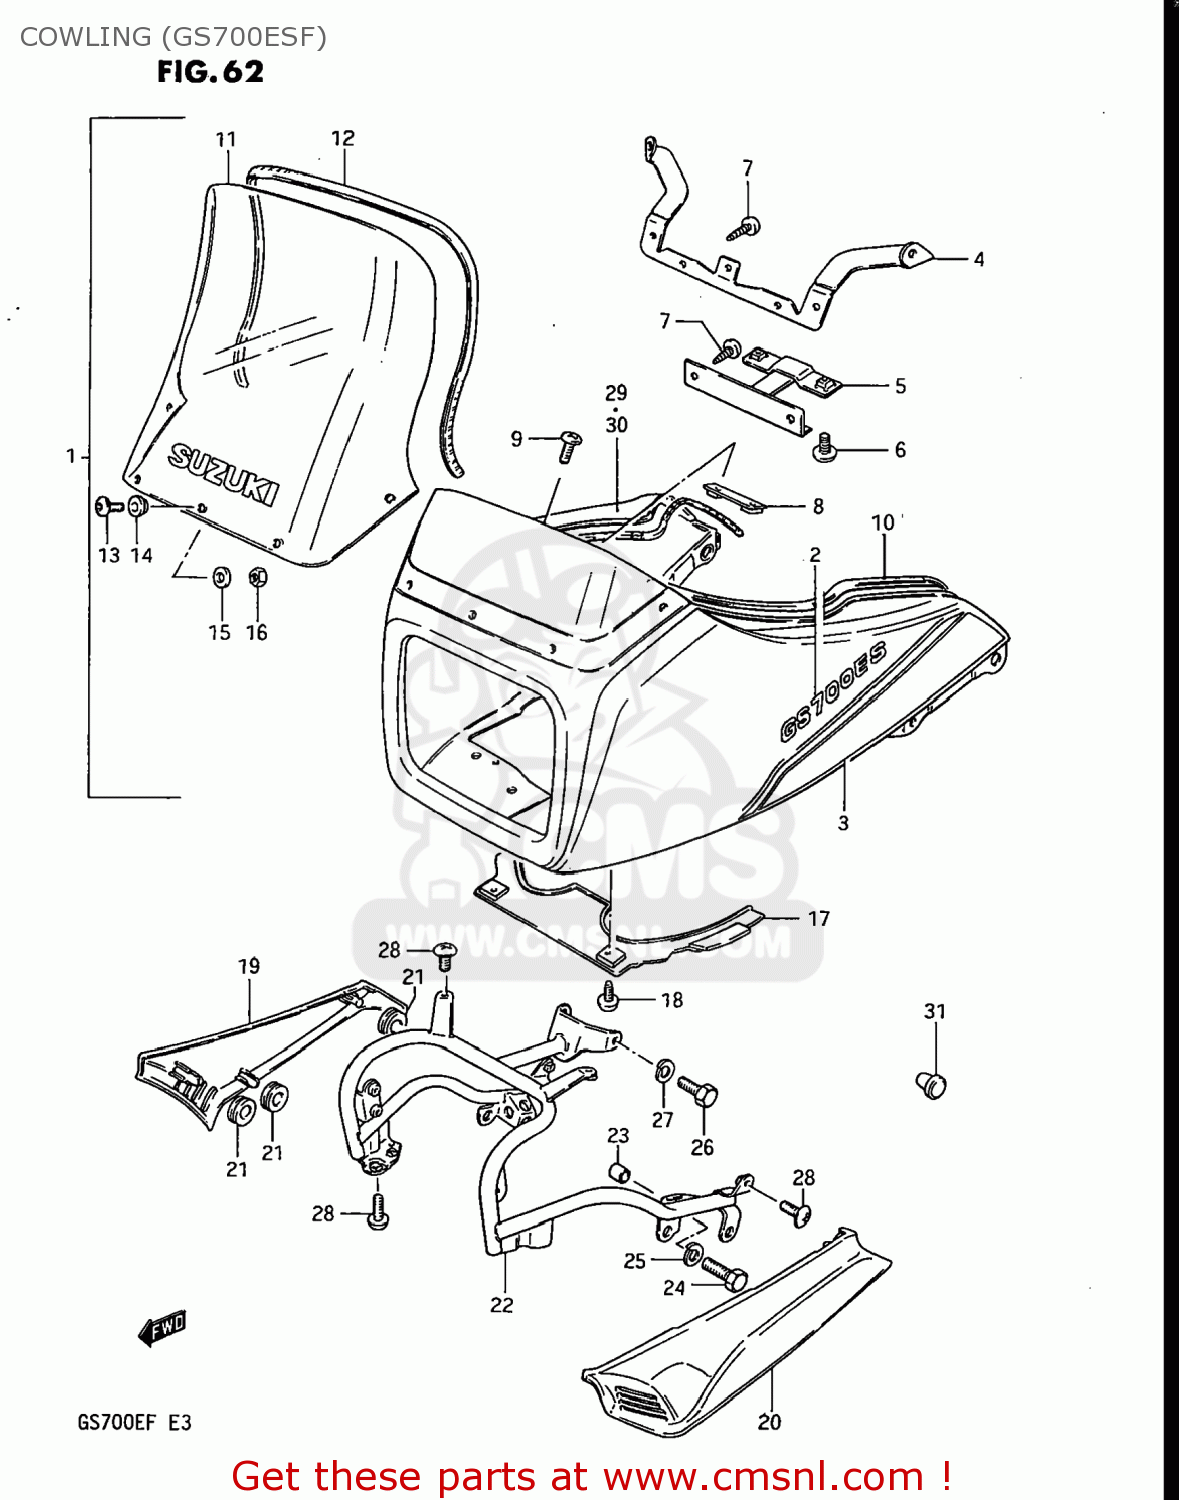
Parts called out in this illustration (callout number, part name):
1	BODY ASSEMBLY,COWLING
2	EMBLEM
3	TAPE SET,COWLING
4	BRACE,COWLING,UPPER
5	BRACE,COWLING,LOWER
6	SCREW
7	SCREW
8	BRACE
9	SCREW
10	MOLDING,FUEL TANK
11	WINDOW,COWLING
12	MOLDING
13	SCREW
14	CUSHION
15	WASHER
16	NUT
17	COVER,COWLING,LOWER
18	SCREW
19	COVER,COWLING,RIGHT
20	COVER,COWLING,LEFT
21	CUSHION
22	BRACE,COWLING
23	SPACER (8.6X13.8X21.5)
24	BOLT
25	WASHER,LOCK,8.
26	BOLT
27	WASHER,LOCK,8.
28	SCREW 6X12
29	TAPE,RIGHT
30	TAPE,LEFT
31	PLUG(OD:12)
